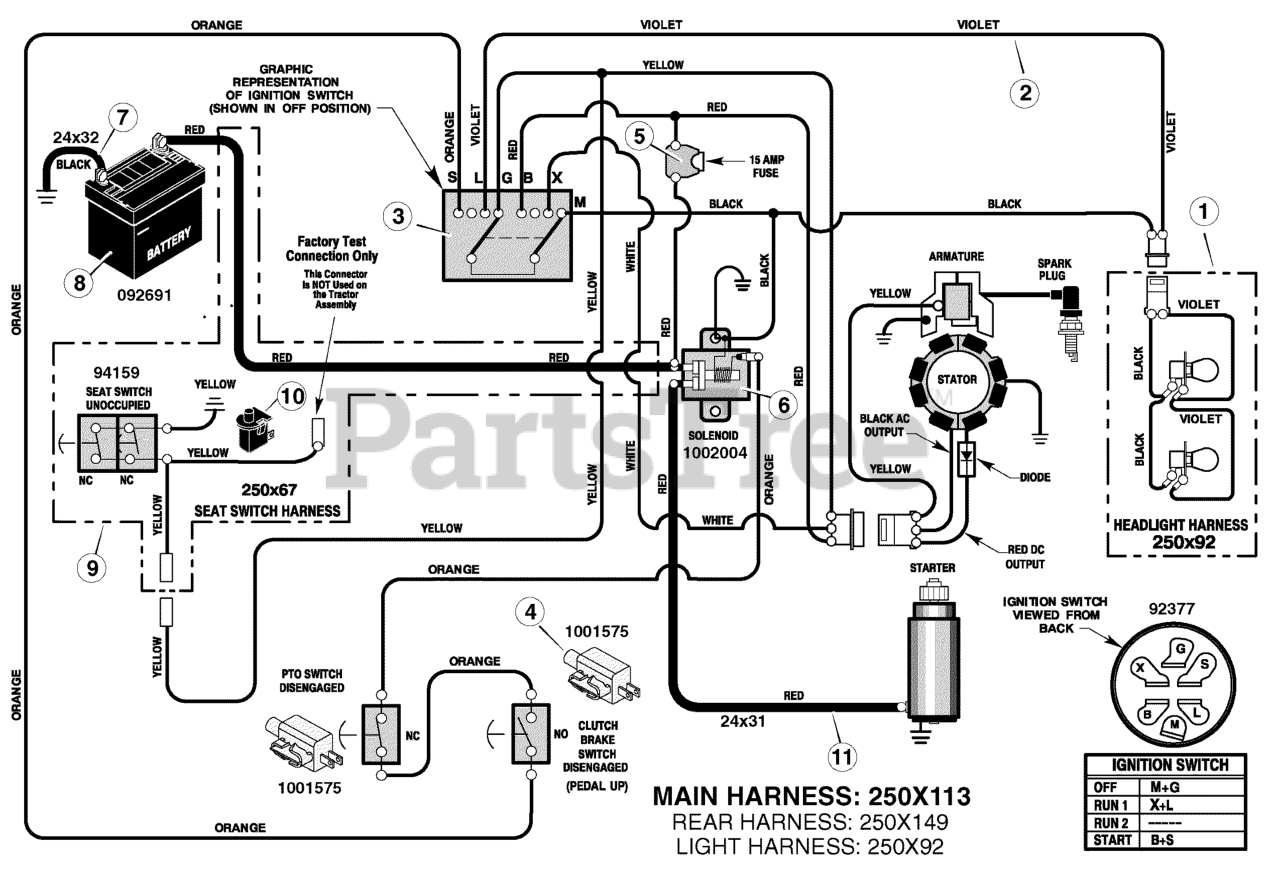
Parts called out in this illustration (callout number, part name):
1	Harness, Light Wire
1	Socket, Light
1	Bulb, Light
2	Harness, Chassis Wire
3	Switch, Ignition
3	Key, Ignition
3	Nut, Hex
3	Cap, Ignition
4	Switch, Limit
5	Holder, Fuse
6	Solenoid
6	Screw, Mounting
6	Locknut
7	Cable, Battery Ground
7	Screw, Ground Cable
8	Battery
8	Bolt, Carriage
8	Wingnut
8	BOOT, Battery Terminal, Positive
9	Harness, Seat Switch Wire
10	Switch, Seat Sensor
